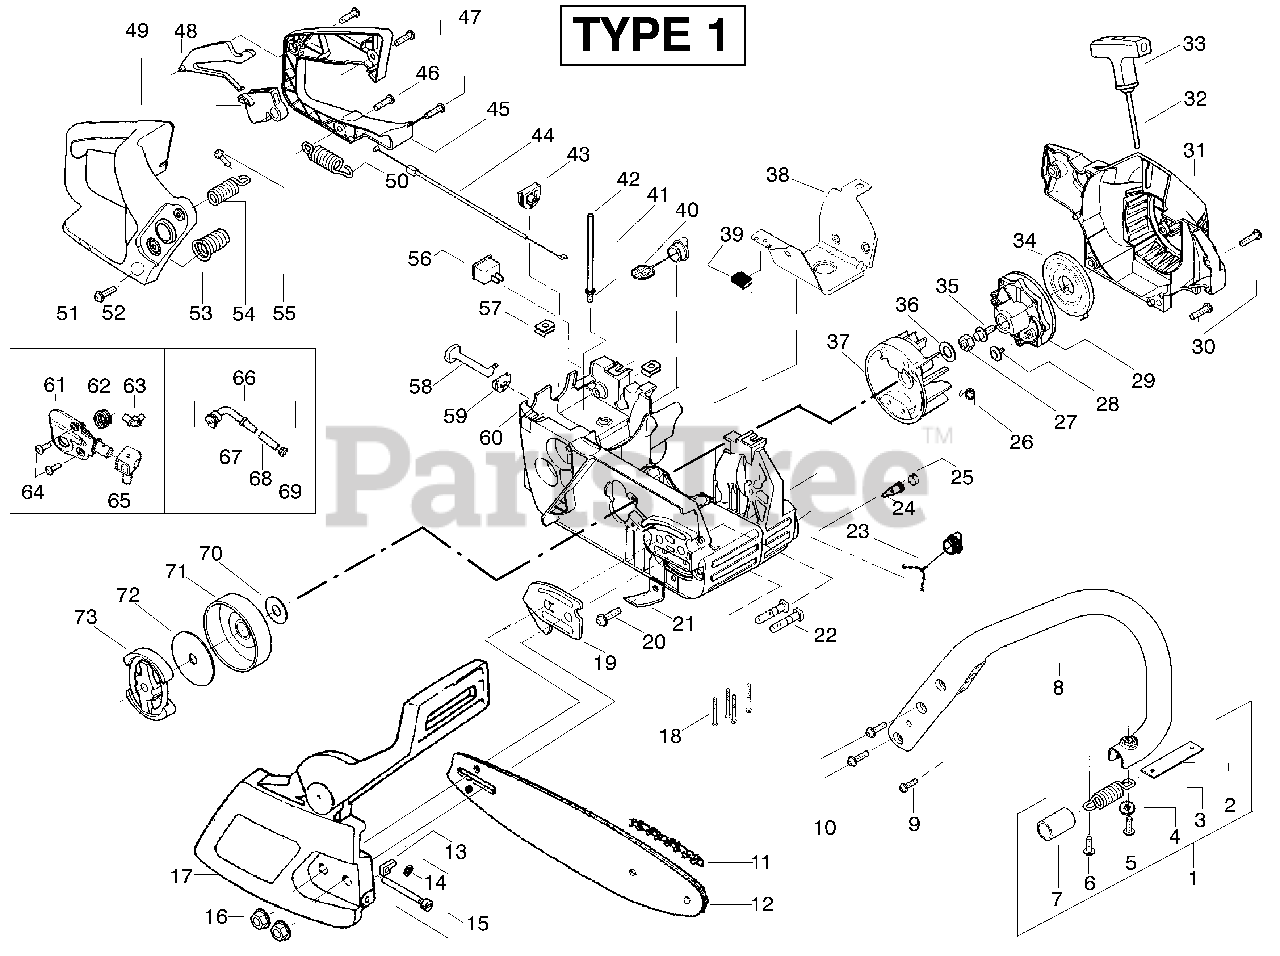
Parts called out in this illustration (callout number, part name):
1	Assy.- Isolator
2	Limiter Strap
3	Spring- Isolator
7	Sleeve-AV Spring
8	Front Handle
11	Chain-18"
13	Pin-Bar Adjust
14	Retainer - Bar Adjust
15	Kit-Bar Adjust
16	Nut-Bar Mounting
17	Kit-Chain Brake
19	Plate-Bar Mounting
21	Chain Catcher
22	Bolt-Bar
23	Oil Cap Ass’y.
24	Check Valve
25	Plug-Bronze Vent
26	Spring-Starter Dog
27	Nut- Flywheel
29	Starter Pulley
31	Fan Housing
32	Kit - Rope
33	Starter Handle
34	Recoil Spring
36	Washer- Flywheel
37	Flywheel Ass’y.
38	Shield - Heat
39	Clip - "U"
40	Fuel Cap Ass’y.
41	Fitting- fuel line
42	Kit-Fuel line
43	Grommet-Cable
44	Cable-Throttle
45	Cover-Rear Handle
48	Throttle Lockout
49	Trigger-Throttle
50	Spring- Isolator
51	Handle - Rear
53	Assy. Isolator - lower
54	Isolator Kit
56	Kit-Switch
57	Nut- "U"-Type
58	Knob-Choke
59	Grommet-Knob
60	Chassis Ass’y.
61	Kit - Oil Pump
62	Gear-Worm Spring
63	Elbow-Oil Pickup
65	Seal Block
66	Oil Pick-up Ass’y
67	Pick-up Oiler
68	Oil Filter
69	Plug-Oil Filter
70	Washer-Thrust
71	Assy.-Clutch Drum w/bearing
72	Washer-Clutch
73	Assy. Clutch
